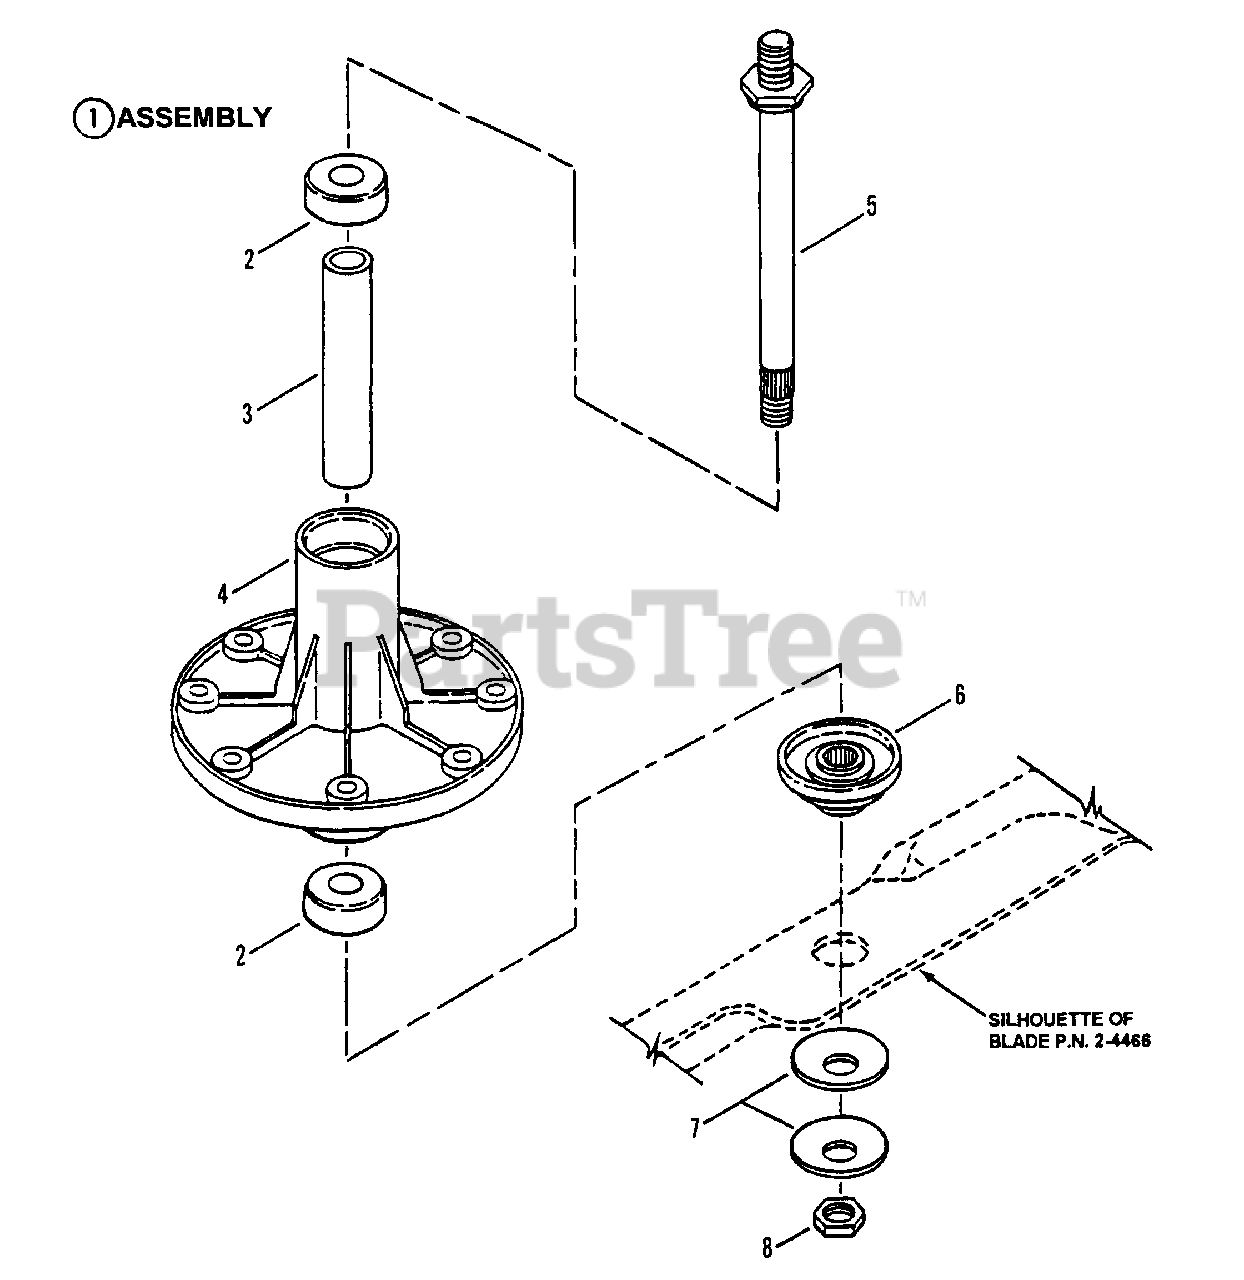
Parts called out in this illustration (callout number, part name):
1	ASSEMBLY, Spindle Housing, 38" Cutting Deck
2	BEARING, Spindle
3	SPACER, Spindle Housing
4	HOUSING, Spindle
5	SPINDLE, 7.019" Long
6	SPACER, Blade
7	WASHER, Belleville, 19/32 I.D. x 1 3/4" O.D.
8	NUT, 9/16-18 Hex Jam
